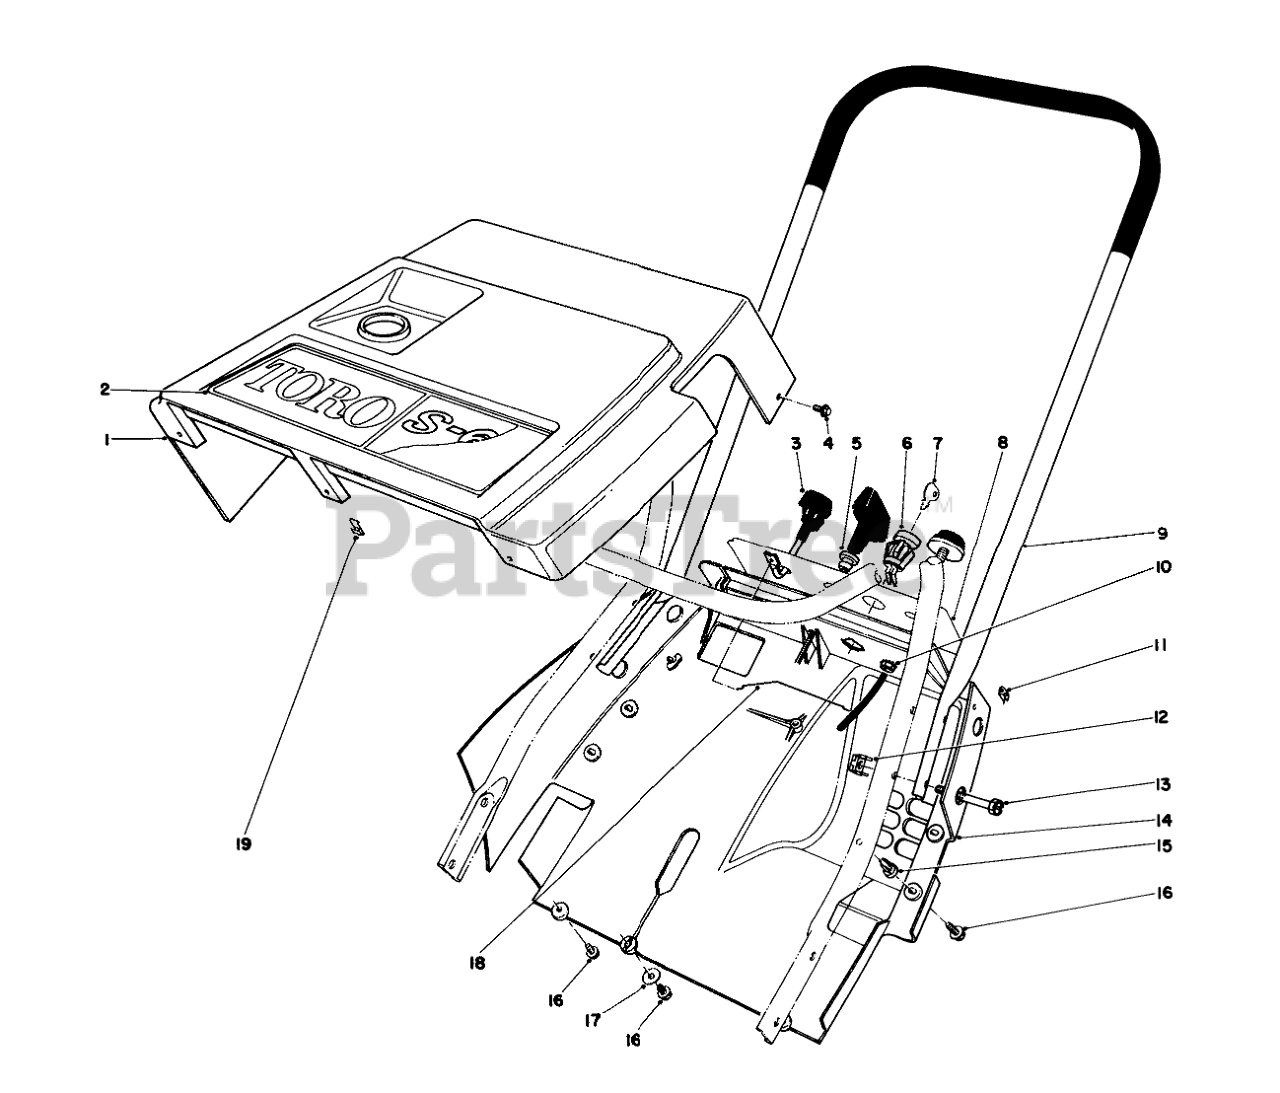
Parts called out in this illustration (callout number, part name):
1	Shroud-Upper
2	TORO DECAL
3	CHOKE CONTROL ASM
4	SCREW-HWHTF
5	GUIDE-ROPE, STARTER
6	SWITCH
7	Key
8	Decal-Control Panel
9	Handle-Upper
10	NUT-KEPS
12	TINNERMAN NUT
13	SCREW-HEX HD SLOT
14	LOWER SHROUD
15	Nut-Push
16	SCREW-HWHTF
17	WASHER-FLAT
18	CONTROL WIRE
19	NUT "U"
